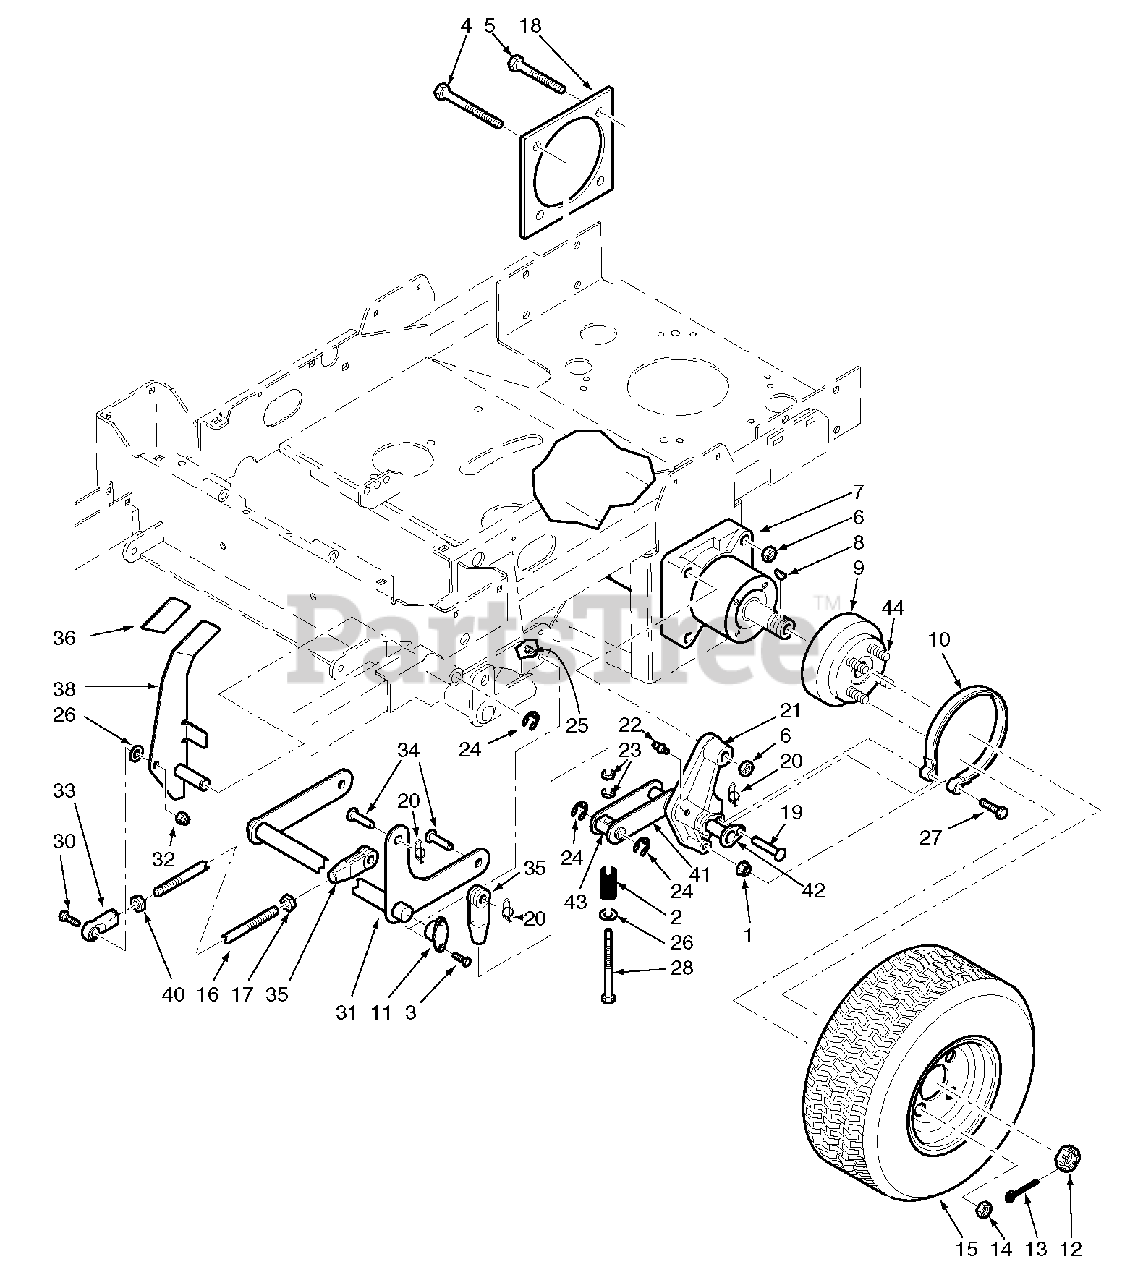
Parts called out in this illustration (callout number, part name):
1	Nut, Serr. Flange 1/2-13
2	Spring
3	Bolt, Hex Head 5/16-18 x 3/4"
4	Bolt, Hex Head 1/2-13 x 3-3/4"
5	Bolt, Hex Head 1/2-13 x 2-1/2"
6	Nut, 1/2-13 Center Lock
7	WHEELMOTOR, LH HGM-15E-3138
8	Key, Woodruff 5/16 x 1"
9	Wheel Hub Assembly
10	Brake Band Assembly
11	Bushing, Self Align
12	Nut, Hex Castle 1.0-20 UNEF
13	Cotter Pin, 9/64 x 1-1/2"
14	Lug Nut, 1/2-20
15	Wheel Assembly 24 x 9.5-12 (48" Cutter Deck)
15	Wheel Assembly 24 x 9.5-12 (52" Cutter Deck)
15	Wheel Assembly 24 x 12-12 (61" Cutter Deck)
15	Rim (48" Cutter Deck)
15	Rim (52" Cutter Deck)
15	Rim (61" Cutter Deck)
15	Tire 24 x 9.5-12 (48 &52)
15	Tire 24 x 12-12 (61)
16	Brake Rod Stud, 3/8-24 x 8.125"
17	Nut, 3/8-24 UNF
18	Plate Weldment, Motor Backing
19	Clevis Pin, 3/8 x 1.93"
20	Pin, Rue Cotter 3/8" Dia.
21	Brake Linkage LH
21	Brake Linkage RH
22	Grease Fitting, 1/4-28
23	Nut, 3/8-24 UNF
24	Retaining Ring, .625" Ext.
25	Nut, Elastic Stop 5/16-18
26	Flatwasher, 3/8-.391 x .938 x .105"
27	Bolt, Hex Head 1/2-13 x 2-1/2"
28	Bolt, Hex Head 3/8-24 x 3-3/4"
29	Cotter Pin, 3/32 x 3/4"
30	Bolt, Hex Head 3/8-16 x 1-1/2"
31	Brake Shaft
32	Nut, Elastic Stop 3/8-16
33	Rod End, 3/8-24 LH Thread
34	Clevis Pin, 3/8 x 1.06"
35	Clevis, 3/8-24
36	Grip, Brake Lever
37	Nut, Serr. Flange 3/8-16
38	Brake Lever
39	Bolt, Hex Head 3/8-16 x 2-3/4"
40	Nut, 3/8-24 UNF-2B LH Thread
41	Lever, Brake
42	Shaft Weldment, Pivot
43	Pin, Pivot
44	Bolt, Serr. Flange 1/2-20 x 4.563"
